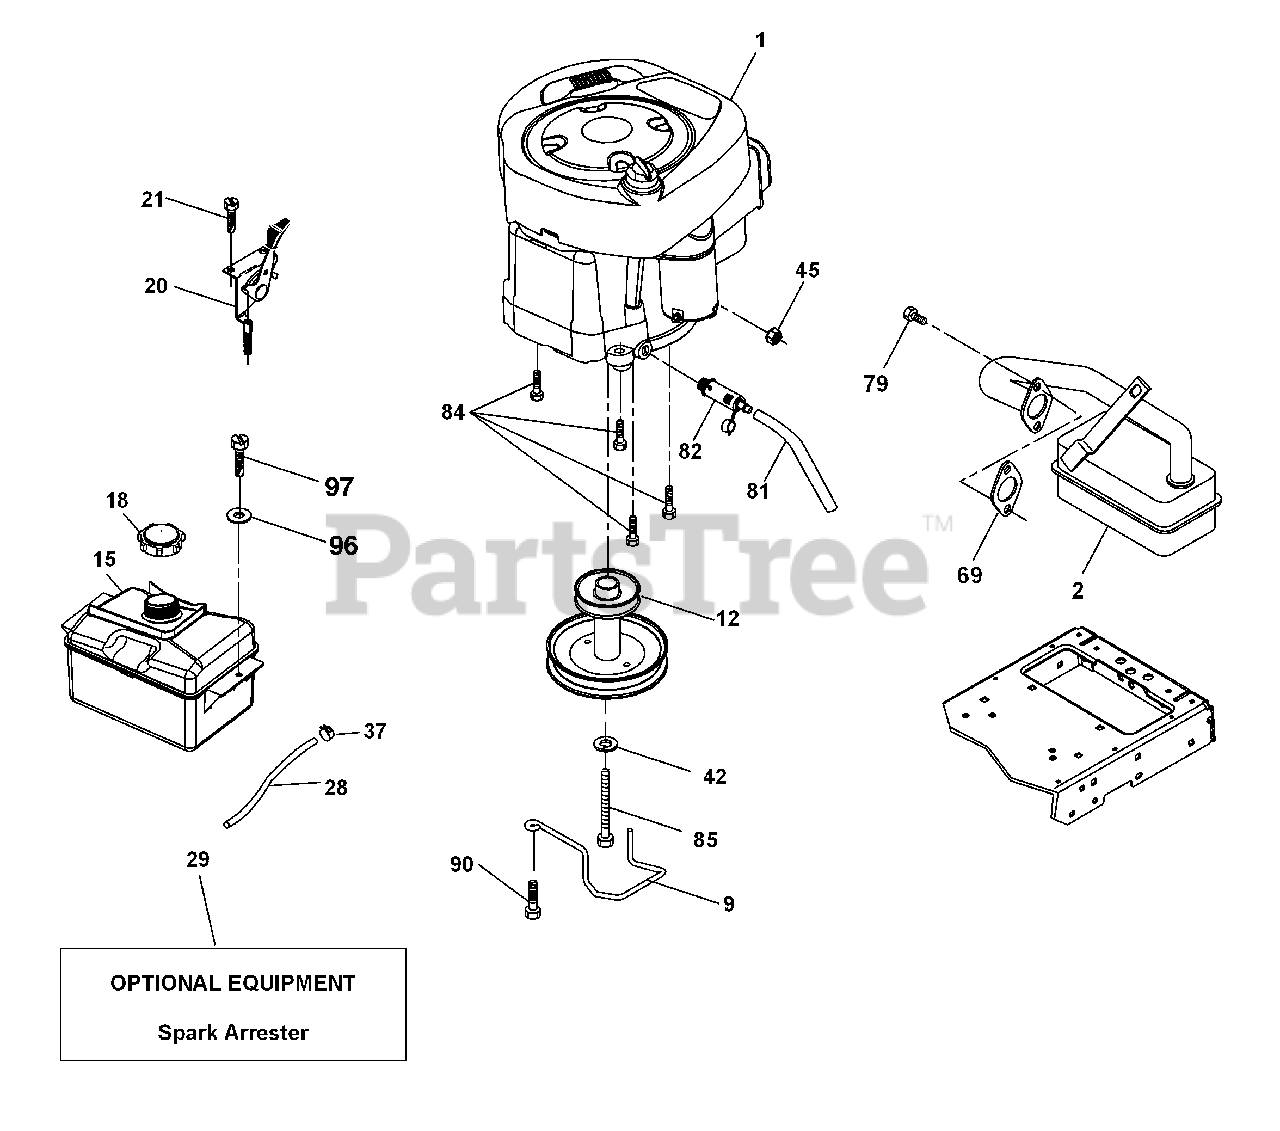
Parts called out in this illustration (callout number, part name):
2	Muffler
9	Keeper Belt Engine
12	Pulley Engine
15	Tank Fuel 1.50
20	Control Throttle/Choke
21	Screw 10 x 3/4 Single Lead-Hex
28	Fuel Line
29	Spark Arrester Kit
37	Clamp Hose
42	Washer Lock 7/16
45	Nut Keps Hex 1/4-20 unc
69	Gasket
79	Screw Socket Hd 5/16-18 x .75
81	Tube Drain Oil Easy
82	Plug Drain Oil
84	Screw 3/8-16 x 1-1/4
85	Bolt Hex 7/16-20 x 4 x Gr. 5-1.5
90	Screw 3/8-16 x 1.0
96	Washer 9/32 x 7/8 x 16 Ga.
97	Screw 1/4-20 x 3/4
